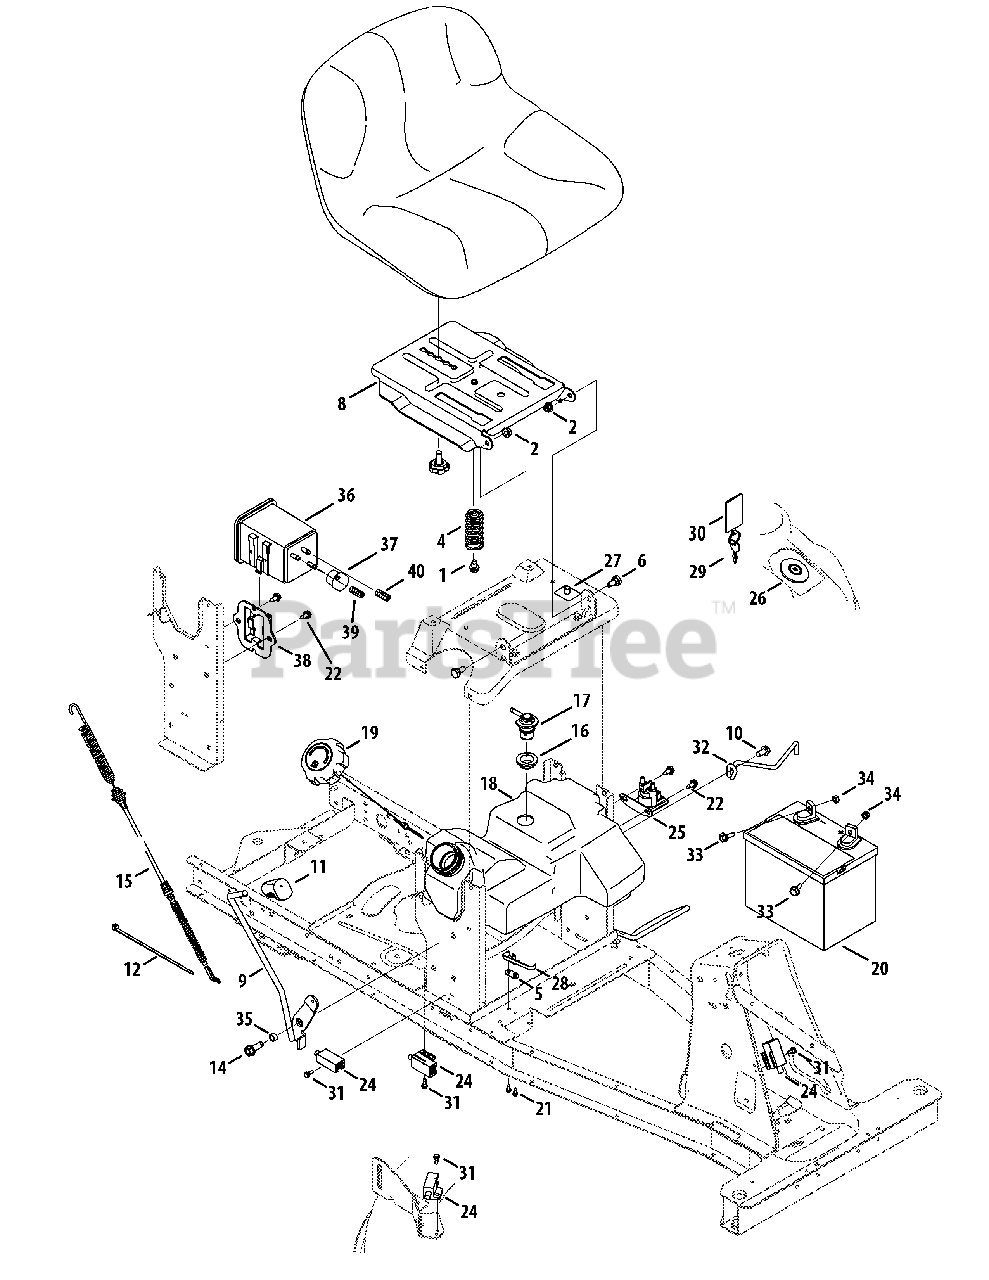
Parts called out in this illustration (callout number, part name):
1	Tap Screw, 5/16-18, 0.500
2	Flange Lock Nut, 5/16-18
3	Knob, 3/8-16, .875
4	Seat Spring
5	Insulator Plate
6	Shoulder Spacer
8	Seat Pivot Bracket
9	PTO Handle Assembly
10	Tap Screw, 5/16-18, .750
11	Handle Grip, 3/8
12	Cable Tie, 3/16 X .05 X 7.4
13	Extension Spring, .50 OD X 4.646 L
14	Tap Screw, 3/8-16, 1.00
15	PTO Cable
16	Rubber Grommet
17	Rollover Valve
18	Fuel Tank, 1-3 Gal.
19	Fuel Cap
20	Battery, 155 CCA
21	Screw, #8
22	Tap Screw, 1/4-20, .625
23	Flange Lock Nut, 1/4-20
24	Interlock Switch
25	Solienoid, 12v
26	Three-Way Key Switch
27	Seat Switch
28	Switch Spring
30	Key Assembly
31	Shoulder Screw, #10-32, .500
32	Battery Holddown Rod
33	Screw, Shoulder, .250 x .150
34	Nut, Sems, 1/4-20
35	Spacer, .380 X .50 X .265
36	Carbon Cannister
37	Cannister Vent Filter
38	Cannister Adapter Bracket
39	Fuel Line, White
40	Fuel Line, Yellow
